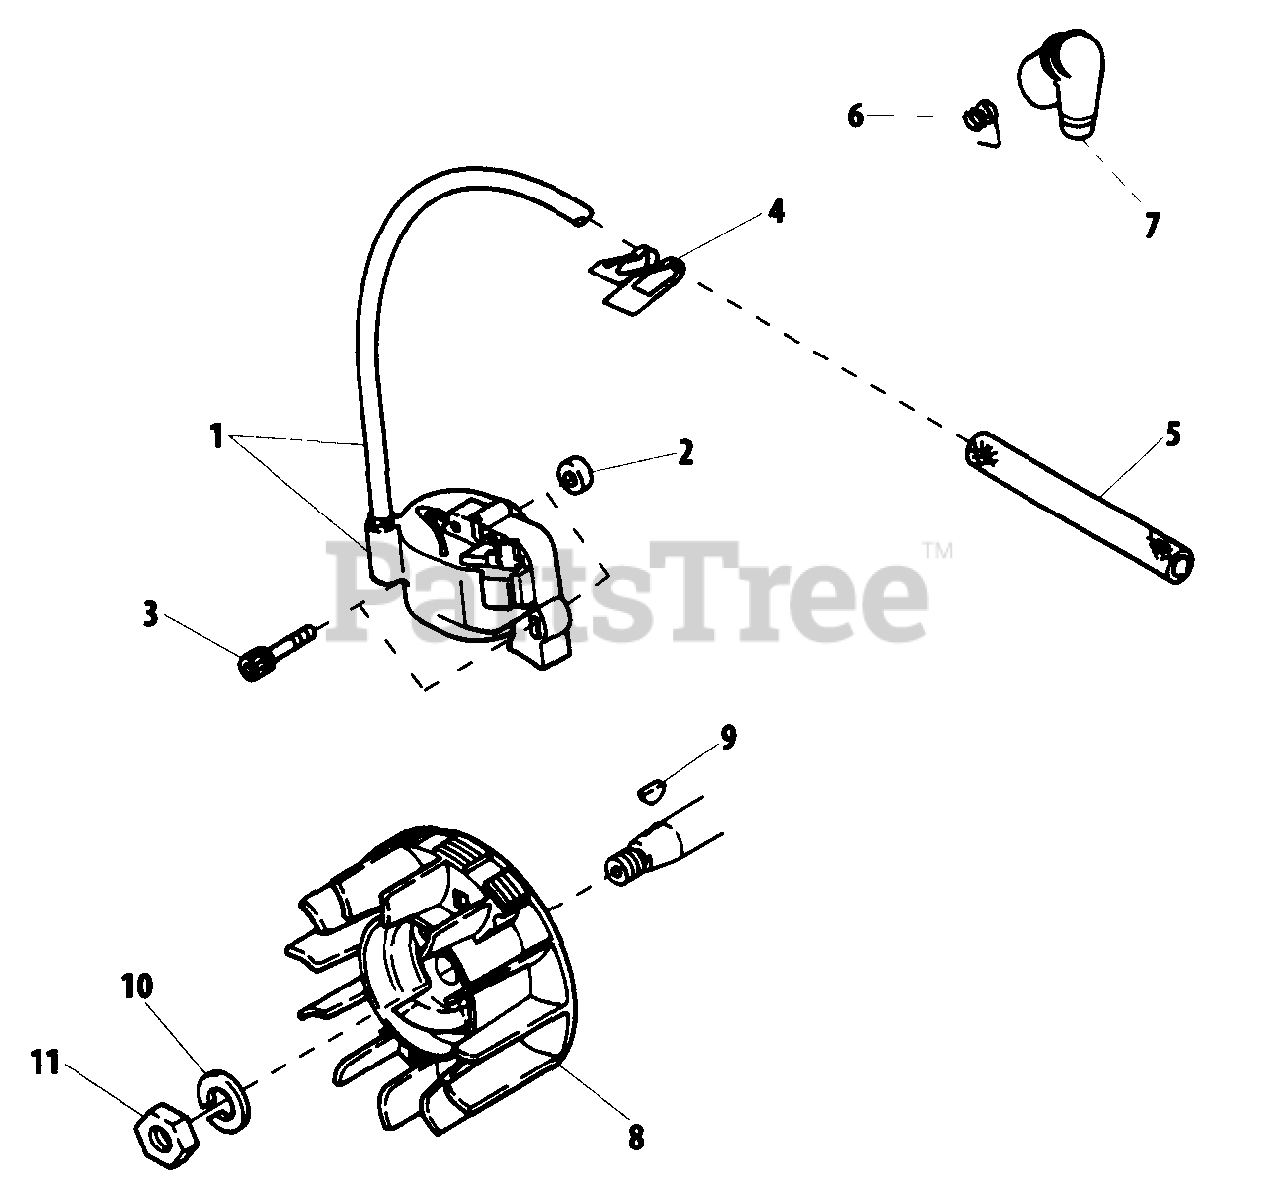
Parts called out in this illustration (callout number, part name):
1	COIL, IGNITION
2	INSULATOR
3	BOLT, ADHESIVE M4×24
4	CLIP
5	TUBE, INSULATOR
6	TERMINAL, SPARK PLUG
7	CAP, SPARK PLUG
8	FLYWHEEL
9	KEY, WOODRUFF 3×10
10	WASHER, SPRING 8
11	NUT
